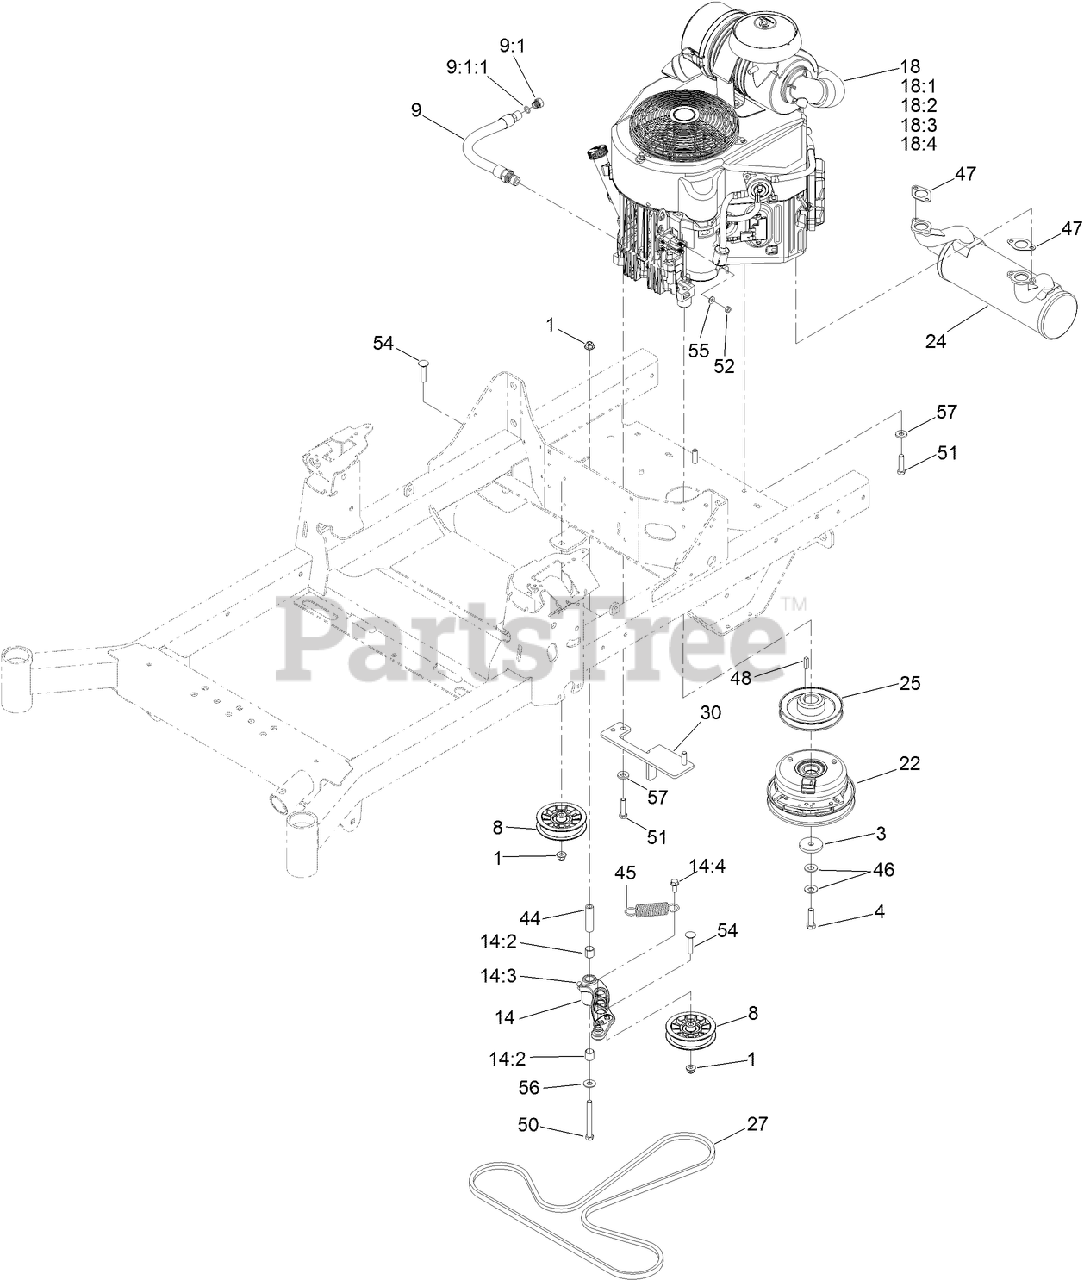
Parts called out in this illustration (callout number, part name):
1	NUT-HF, NI
3	WASHER-CLUTCH
4	SCREW-HH
8	PULLEY-FLAT
9	ENGINE OIL DRAIN HOSE ASM
9:1	PLUG-HH
9:1:1	O-RING
14	IDLER ARM ASM
14:2	SLEEVE-BEARING
14:3	FITTING-GREASE, 90 DEG
14:4	SCREW-HWHTF
18:1	KAWASAKI 49065-7007 ENGINE OIL FILTER
18:2	KAWASAKI 49019-7005 FUEL FILTER
18:3	KAWASAKI 11013-7045 SAFETY FILTER
18:4	KAWASAKI 11013-7044 ENGINE AIR FILTER
22	CLUTCH
24	MUFFLER
25	SHEAVE (W/HUB)
27	BELT-V
30	ANCHOR-CLUTCH
44	BUSHING-PIVOT, IDLER
45	SPRING-EXTENSION
46	WASHER-SPRING
47	GASKET-EXHAUST
50	SCREW-HH
51	SCREW-HH
52	NUT-HEX
54	SCREW-CARR
55	WASHER-FLAT
56	WASHER-FLAT
57	WASHER-BELLEVILLE
